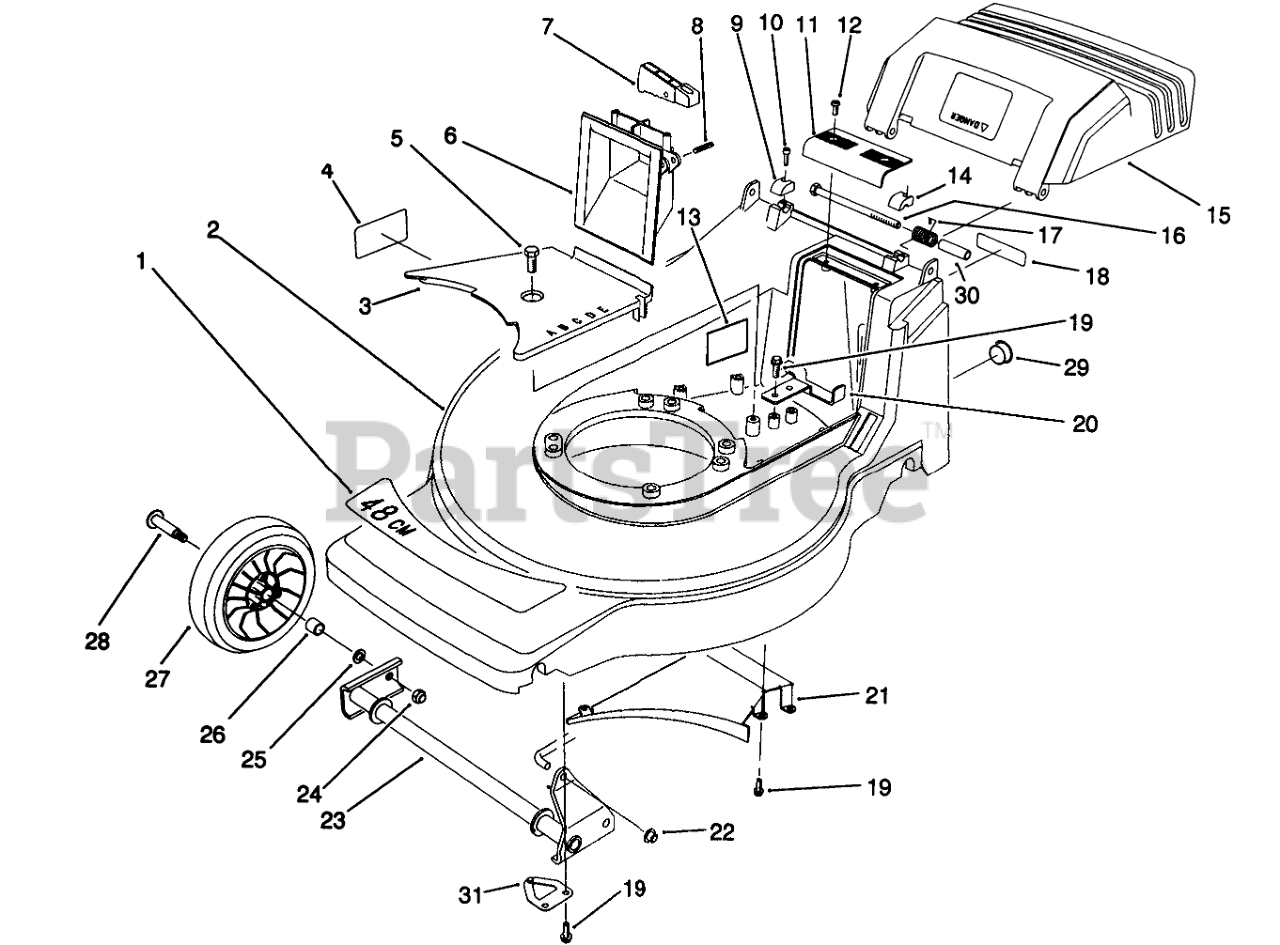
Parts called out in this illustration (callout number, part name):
1	DECAL - DECK
2	Housing-48cm
3	BELT COVER
4	Decal Danger
5	SCREW-HWHTF
6	GRIP - LOWER
7	TRIGGER - HOC
8	PIN-SPIRAL
9	CAP-HINGE BOLT, RH
10	SCREW-HSH
11	GRIP-UPPER
12	SCREW-PPH, PLASTITE
13	Decal-Noise
14	CAP-HINGE BOLT, LH
15	Door-Discharge
16	SCREW-HH
17	DOOR SPRING
18	DECAL FRENCH REGUL.
19	SCREW-HWH
20	REAR BELT GUIDE
21	Ramp-Discharge
22	NUT-PUSH
23	FRONT PIVOT WA
24	NUT-HEX
25	WASHER
26	BUSHING
27	Wheel & Tire Assembly (Incl. Ref. #26)
28	BOLT-WHEEL
29	DOME PLUG (DP-1000)
30	SPACER-DOOR
31	SHAFT RETAINER ASM
